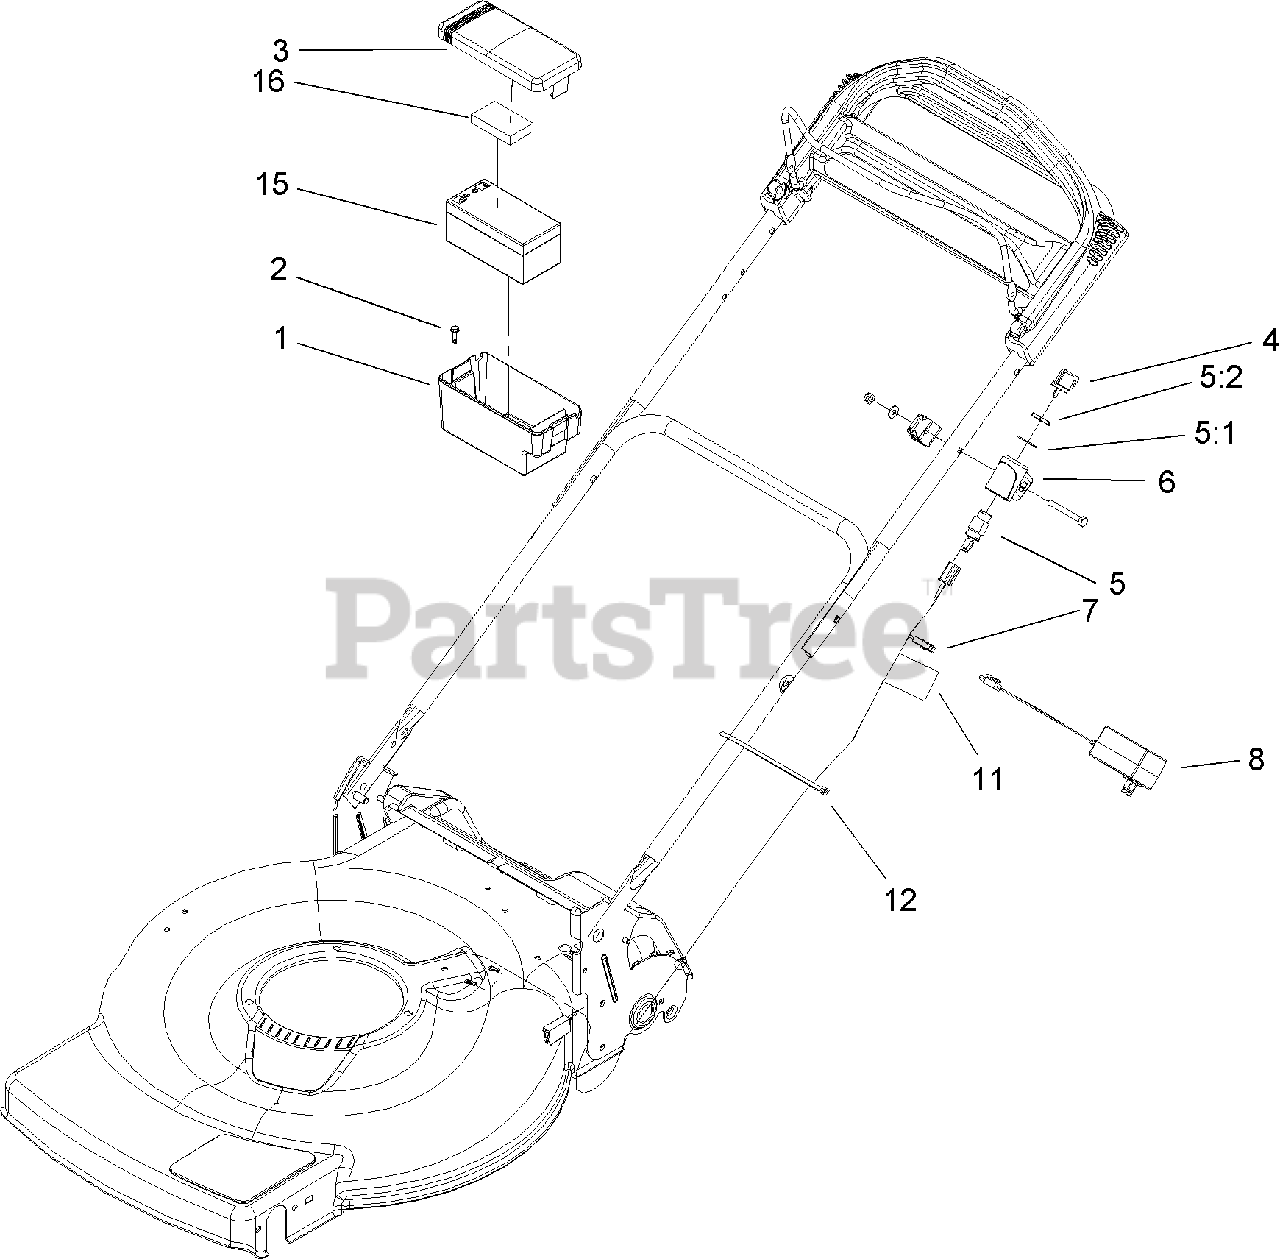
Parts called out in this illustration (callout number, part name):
1	BOX-BATTERY
2	SCREW-TEK
3	COVER-BATTERY
5	SWITCH-STARTER
5:1	WASHER-TOOTH
6	Mount-Switch
7	HARNESS-WIRE
8	CHARGER-12 VOLT
11	DECAL-HARNESS
12	STRAP-TIE
15	BATTERY-12 VOLT
16	FOAM-BATTERY, TOP
